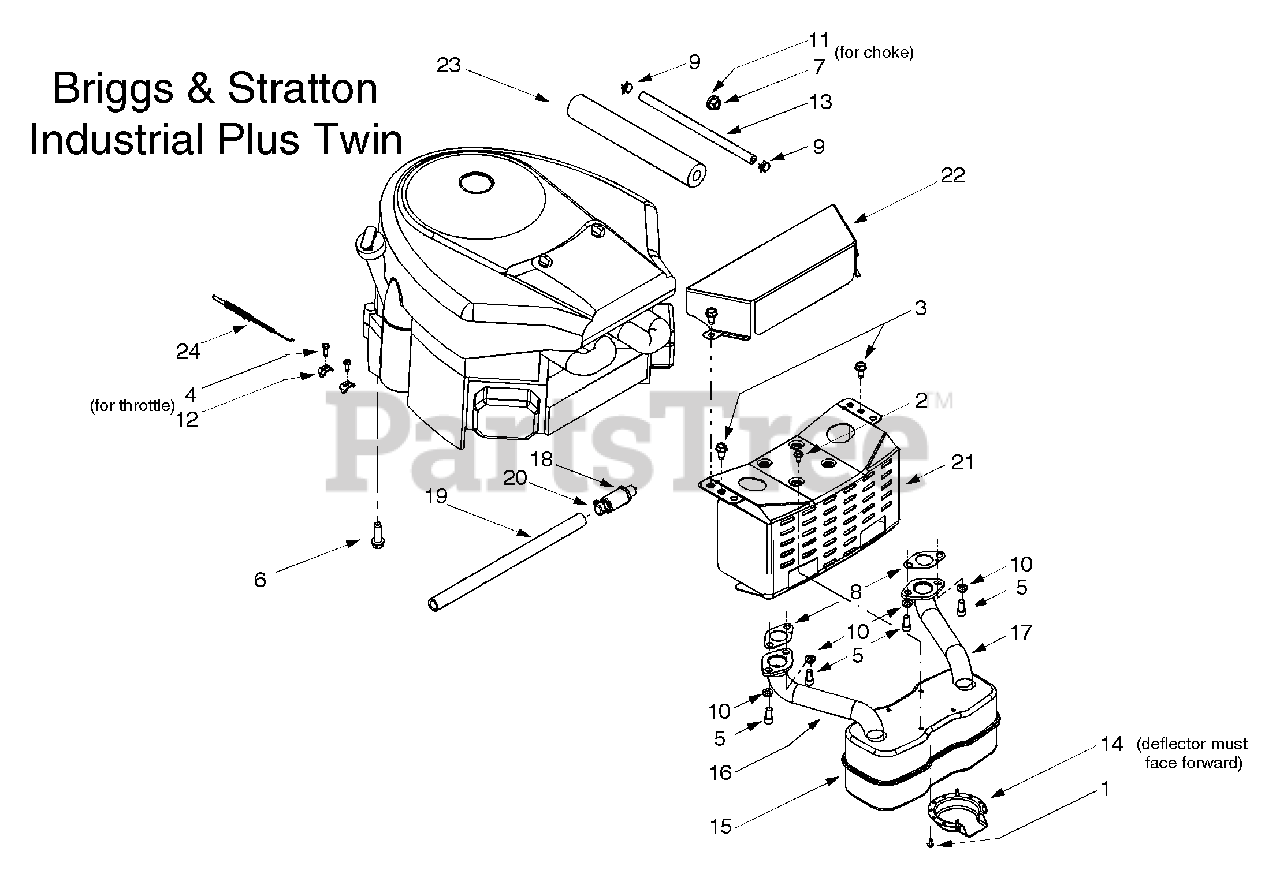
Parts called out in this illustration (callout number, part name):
1	Self-tapping Screw, #8-18 x .5
2	Self-tapping Screw, 1/4-20 x .5
3	Self-tapping Screw, 5/16-18 x .625
4	Screw, #10-32 x .625
5	Socket Cap Screw, 5/16-18 x .625
6	Self-tapping Screw, 3/8-16 x 1.25
7	Hex Nut, 3/8-16
8	Exhaust Gasket
9	Hose Clamp
10	Lock Washer, 5/16
11	Flat Washer, .406 x ..875 x .059
12	Casing Clamp
13	Fuel Line Hose
14	Muffler Deflector
15	Muffler, Twin Inlet
16	RH Exhaust Pipe
17	LH Exhaust Pipe
18	Oil Drain Valve
19	Oil Drain Hose
20	Oil Drain Cap
21	Muffler Heat Shield
22	Engine Heat Shield
23	Foam (Fits over fuel line)
24	THROTTLE CABLE
27	Casing Clamp
28	Muffler, Single Inlet
29	Hex Sems Nut, 1/4-20
31	Extension Spring, .275 x 1.25
